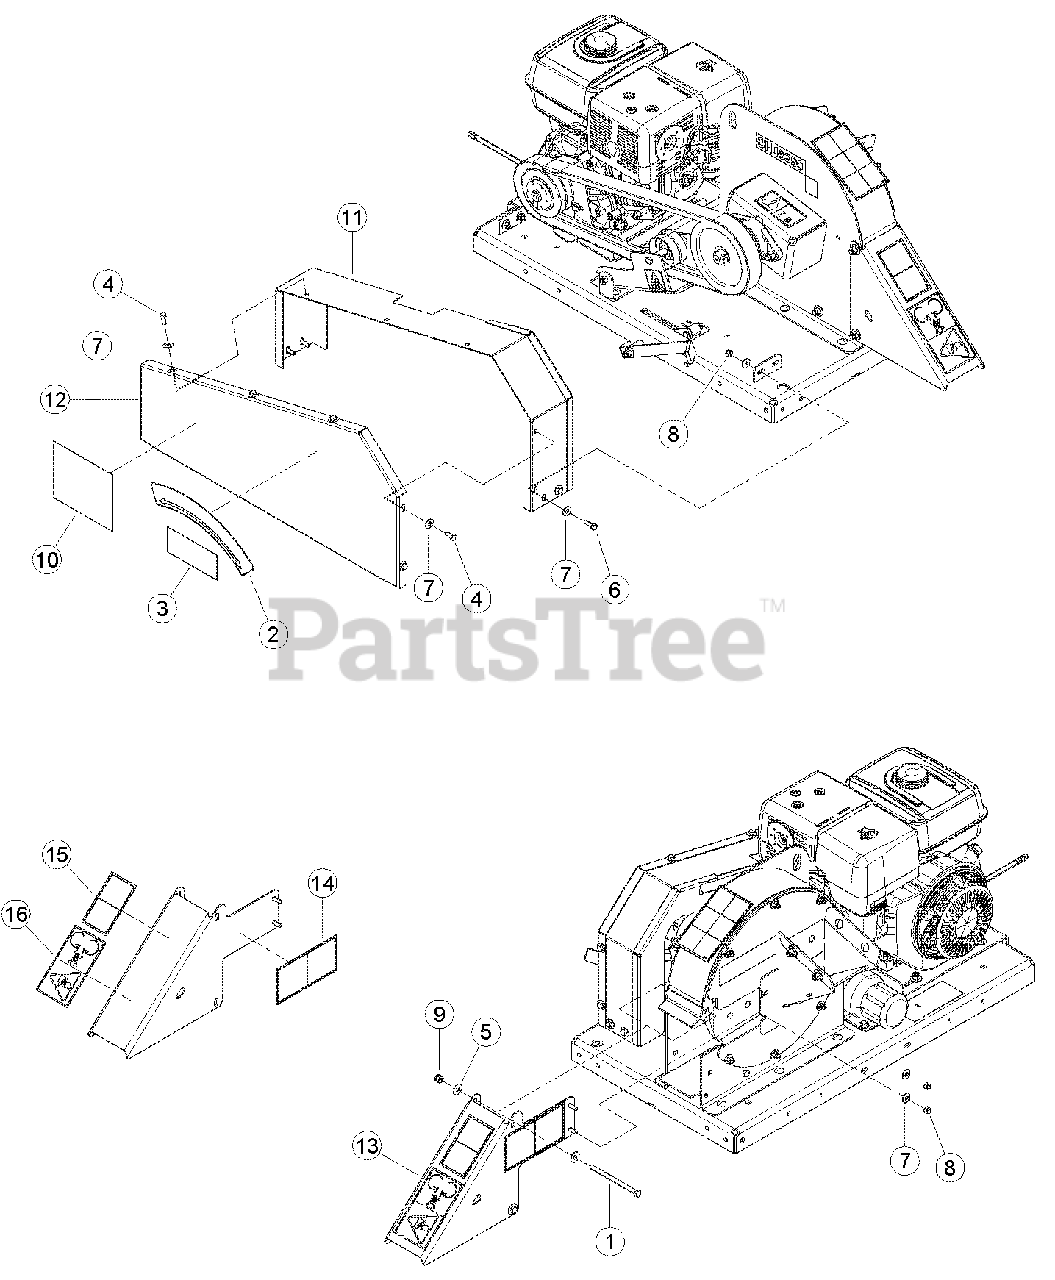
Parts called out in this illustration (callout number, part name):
1	BOLT, 3/8 X 5-1/2 HEX HD GR5 ZP
2	DECAL, START/ENGAGE
3	DECAL, MUTILINGUAL MANUAL
4	BOLT, 5/16 X 3/4 HEX HD GR5 ZP
5	WASHER, 3/8 FLAT ZP
6	BOLT, 5/16 X 1 HEX HD GR5 NC ZP
7	WASHER, 5/16 FLAT ZP
8	NUT, 5/16 NE NYLOCK ZP
9	NUT, 3/8 NE NYLOCK ZP
10	DECAL, CRARY BEARCAT 8.19 X 6.45
10	DECAL, ECHO BEARCAT 8.19 X 6.52
11	WELDMENT, SHIELD
12	SHIELD, BELT
13	ASSEMBLY, DISCHARGE CAP, SERVICE PART
14	DECAL, KNIFE ACCESS ISO
15	DECAL, DISCHARGE ISO
16	DECAL, BLADE DANGER ISO
